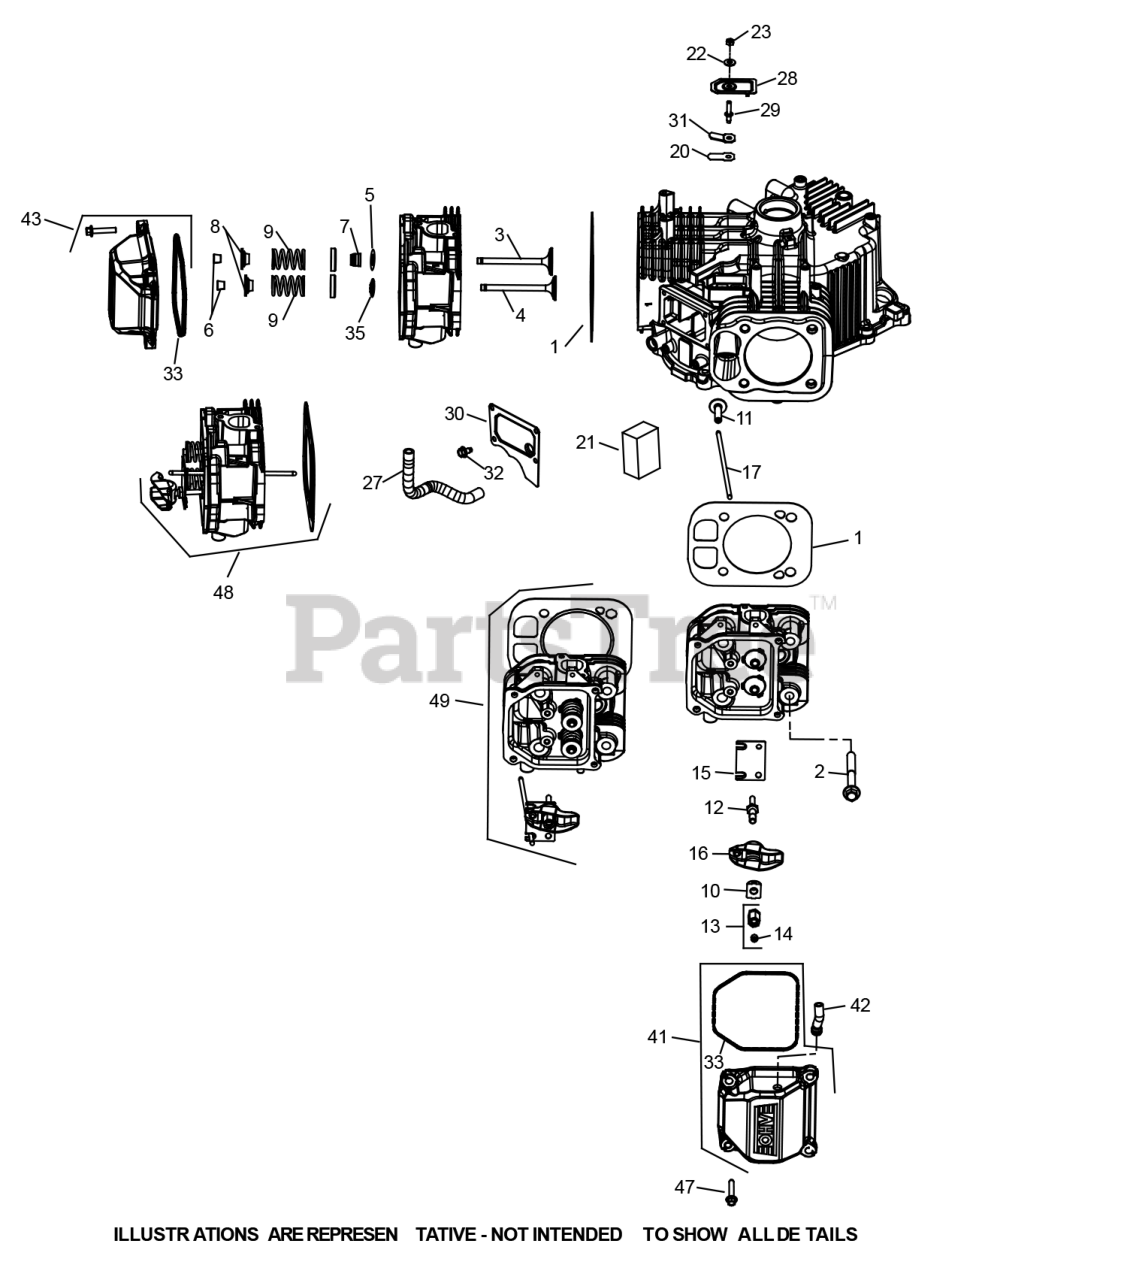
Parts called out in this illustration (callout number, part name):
1	GASKET KIT-CYL HEA
2	SCREW-HEX FLG M10X1.5-6X90
3	INTAKE VALVE .25
4	EXHAUST VALVE
4	EXHAUST VALVE .25
6	KIT-RETAINER
7	VALVE STEM SEAL
8	VALVE CAP SPRING
10	PIVOT- ROCKER ARM
11	TAPPET-PUSH ROD
13	NUT ASSEMBLY-ROCKER
20	BREATHER REED
21	BREATHER FILTER
22	SEALING WASHER
27	BREATHER HOSE
28	COVER-BREATHER REED
29	STUD-BRETHR REED C
30	COVER-BREATHER FILTE
31	RETAINER-BREATHER
33	O-RING VLV CVR
35	VALVE GUIDE RETAINER
41	KIT-ROCKER COVER
42	HOSE KIT-FUEL PUMP
43	COVER KIT-ROCKER
47	SCREW-HEX FLANGE M6x31.625
48	CYLINDER HEAD #1
49	CYLINDER HEAD #2
